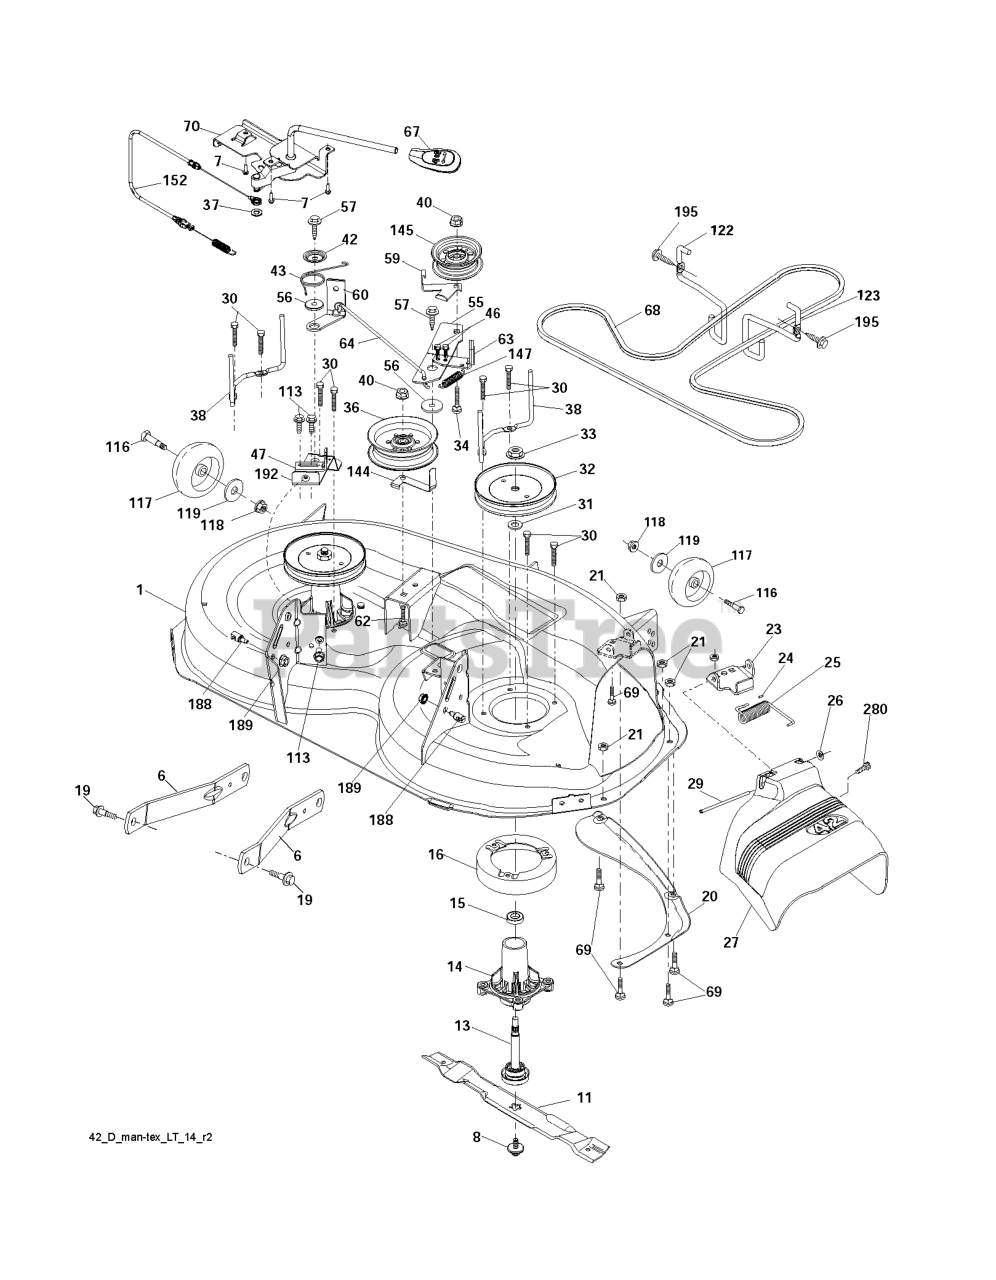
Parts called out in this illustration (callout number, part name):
1	DECK.WELDMENT.42"
6	ARM.SUSPENSION.MOWER.R
7	SCREW.#10 X 0.750.BOS
8	BOLT.WASHER.ASM.7/16-2
11	42" HI-LIFT BLADE
13	SHAFT.ASM.MDRL.N/GREASE.38
14	RP.HOUSING.MANDREL.4PT.
16	STRIPPER.MANDREL.ROUND.BLACK
19	BOLT.SHOULDER
20	BAFFLE.VORTEX
21	LOCKNUT
23	BRKT.DEFLECTOR.38"2005+
24	CAP-SLEEVE LT
25	SPRING.TORSION.DEFLECT
26	NUT PUSH M
27	DEFLECTOR ASM.42"TEX.FRENCH
29	ROD.HINGE
30	SCREW, WASHER HEAD
31	WASHER.SPACER.MANDREL
32	PULLEY.MANDREL.5.438.PD
33	NUT.FLANGE.LOCK.TOP
34	BOLT.3/8-16X1.50
36	PULLEY.IDLER.2006
37	WASHER
38	KEEPER.BELT.LH.MANDREL
40	NUT LOCK FLG 3/8-16 UNC
42	SPRING.TORSION.BRAKE
43	SRPING.TORSION.RETAINE
46	SCREW.1/4-20X5/8
47	BRKT.CLUTCH.CABLE
56	SPACER.RETAINER
57	SCREW 3/8-16X1
59	GUARD, BELT
60	ARM BRAKE MOWER
63	ARM BRAKE MOWER
64	LINK BRAKE
67	HANDLE.CLUTCH.CABLE.LT
68	BELT.DRIVE.MOWER.TEX.42"
69	BOLT
70	CLUTCH.ASM.MANUAL.LT.PRED
113	BOLT.5/16HEX.WHS.HD
115	BOLT.CARR.5/16-18X5/8.SHORT
116	BOLT M
117	WHEEL.GAGE.HALF.SPOKED
118	LOCKNUT
119	WASHER.5/16.FLAT.STE.STD.
122	KEEPER BELT ENGINE LH
123	KEEPER BELT RH
144	KEEPER.BELT.MOWER
145	PULLEY.IDLER.48"PRIMARY
147	RETURN SPRING
152	CLUTCH CABLE
188	STUD.FASTNER.W/ANTI-ROTATE
189	NUT LOCK HEX FLANGE 5/16-18
192	BRKT.BRAKE.STAND.LH.
195	SCREW, 3/8-16X3/4
280	SCREW 3/8-16X1/2
